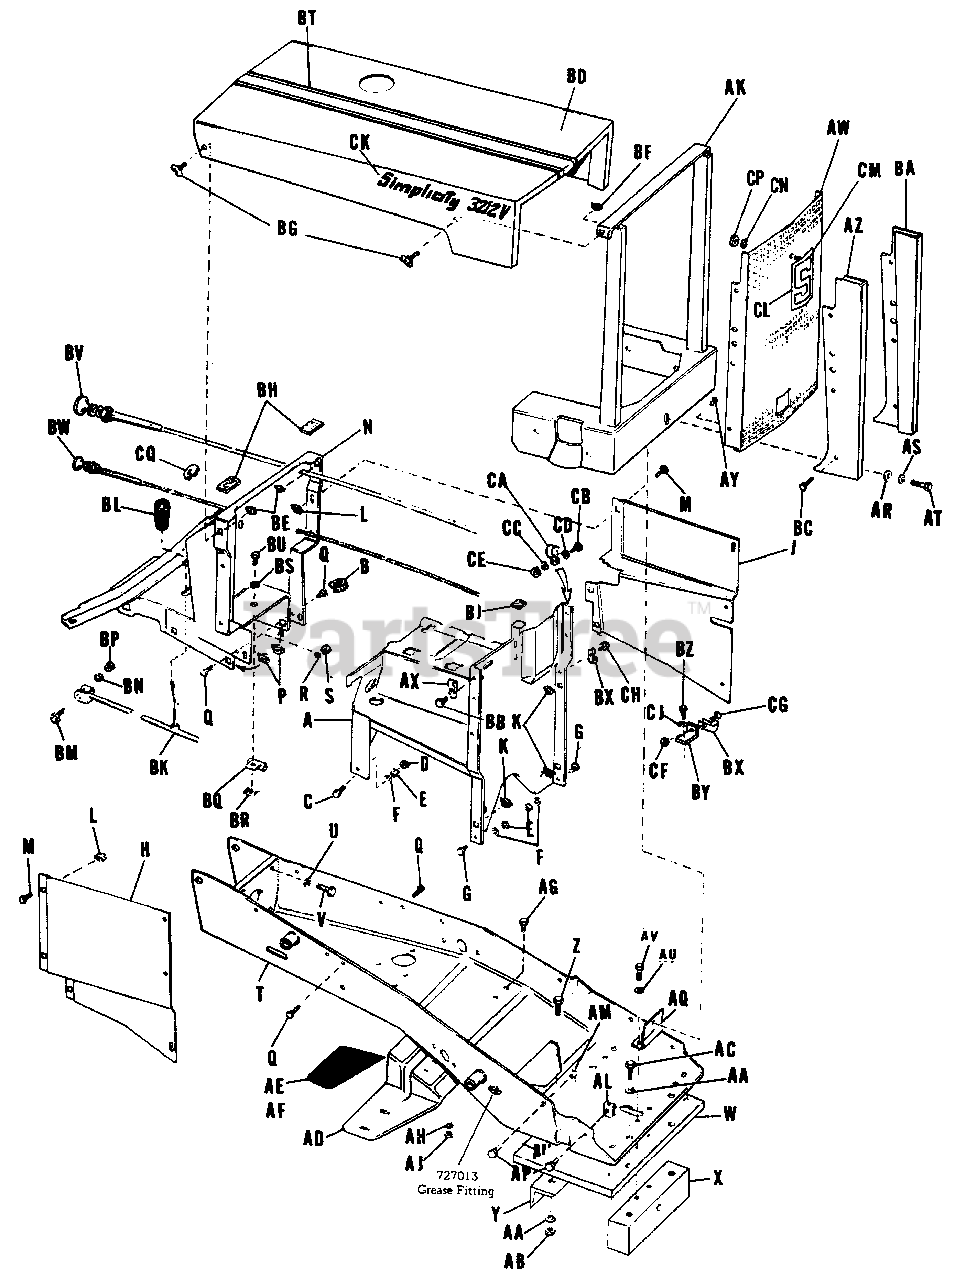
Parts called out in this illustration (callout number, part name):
A	Support Assembly, Fuel Tank & Battery
B	Steering Bushing
C	Hex. Cap Screw, 5/16"-18 x 1-1/4"
D	Full Lock Hex. Nut, 5/16"-18
E	Full Hex. Nut, 5/16"-18
F	Lock Washer, 5/16"
G	Hex. Cap Screw, 5/16"-18 x 5/8"
H	R.H. Side Panel
J	L.H. Side Panel
K	Nut Retainer
L	Nut Retainer
M	Hex. Cap Screw, 1/4"-20 x 5/8"
N	Inst. Panel Assembly
P	Nut Retainer (Frame Cover)
Q	Hex. Cap Screw, 1/4"-20 x 1/2"
R	Lock Washer, 1/4"
S	Full Hex. Nut, 1/4"-20
T	Frame Assembly
U	Lock Washer, 7/16"
V	Hex. Cap Screw, 7/16"-14 x 1 1/2"
W	Base Weight
X	Front Support, 1 3/4" x 2 1/2" x 8 5/8"
Y	Angle Assembly (Frame Rear)
Z	Hex. Cap Screw, 7/16"-14 x 1 1/2"
AA	Lock Washer, 7/16"
AB	Full Hex. Nut, 7/16"-14
AC	Hex. Cap Screw, 7/16"-20 x 1 1/2"
AD	Foot Rest
AE	L.H. Foot Rest Pad
AF	R.H. Foot Rest Pad
AG	Hex. Cap Screw, 3/8"-16 x 3/4"
AH	Lock Washer, 3/8"
AJ	Full Hex. Nut, 3/8"-16
AK	Cover & Tube Assembly
AL	Retainer Nut (Front)
AM	Retainer Nut (Rear)
AN	Simplicity & Number 3212 V Film L.H.
AP	Hex. Screw, Whiz-Lock Flange, 5/16"-18 x 3/4"
AQ	Bracket Assembly
AR	Plain Washer, 5/16"
AS	Lock Washer, 5/16"
AT	Hex. Cap Screw, 5/16"-18 x 1-1/4"
AU	Lock Washer, 5/16"
AV	Hex. Cap Screw, 5/16"-18 x 1 1/2"
AY	Self Tapping Screw, #10 x 1/2"
AZ	R.H. Side Plate
BA	L.H. Side Plate
BB	Self Tapping Screw, 10-24 x 1/2"
BC	Self Tapping Screw, 10 x 1/2"
BE	Nut Retainer (Rear)
BF	Nut Reatiner (Front)
BG	Thumb Screw
BK	Shifter Rod Assembly
BM	Hex. Cap Screw, 5/16"-18 x 1-1/2"
BN	Lock Washer, 5/16"
BP	Full Hex. Nut, 5/16"-18
BQ	Shift Rod Guide Assembly
BR	Retainer Nut
BS	Lock Washer, 1/4"
BT	Hood Strip
BU	Hex. Cap Screw, 1/4"-20 x 5/8"
BV	Throttle Control
BW	Choke Control
BX	Bowden Wire Clip
BY	Throttle Cable Bracket
BZ	Self Tapping Screw, 1/4"-20 x 5/8"
CB	Hex. Cap Screw, 1/4"-20 x 5/8"
CC	Lock Washer, 1/4"
CD	Plain Washer, 1/4"
CE	Full Hex. Nut, 1/4"-20
CF	Full Hex. Nut, 10-32
CG	Mach. Rd. Hd. Screw, 10-32 x 3/8"
CH	Self Tapping Rd. Hd. Screw, 10-24 x 1/2"
CJ	Lock Washer 1/4"
CK	Simplicity & Number 3212 V Film
CL	Plate, Assembly
CM	Emblem "S"
CN	Washer Lock No. 12
CP	Hex. Nut 10-24
